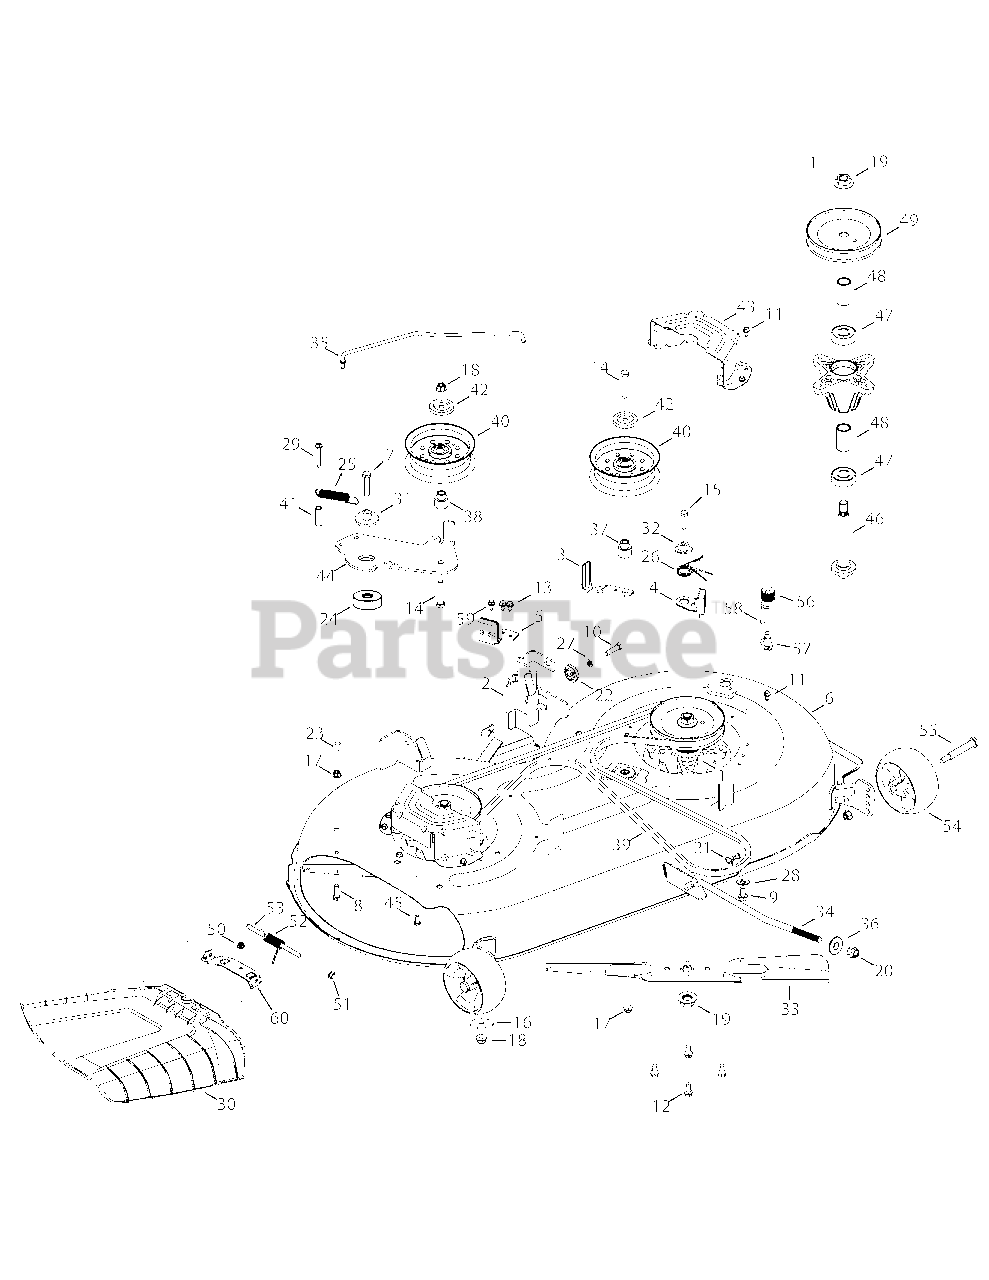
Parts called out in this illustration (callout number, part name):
1	Spindle Ass’y, Pulley, 6.2 Dia
2	Bracket Ass’y, Deck, Hanger LH
3	Belt Keeper
4	Brake Assembly, Deck, LH
5	Brake Assembly, Deck, RH
6	Deck, 42"
7	Hex Screw, 3/8-16 x 1.75
8	Hex Cap Screw, 5/16-18 x 1.00
9	Screw, Self-tapping, 5/16-18, .750
10	Hex Screw, 5/16-18, 1.25, Gr5, Std
11	Screw, Self-tapping, 1/4-20, 0.500
12	Screw, 5/16-18 x 0.750
13	Screw, M6-1 x .625
14	Hex Screw, 3/8-16, 2.00, Gr8, Std
15	Hex cap Screw, 5/16-18 x 1.25
16	Flat Washer, .406 x 1.50 x .105
17	Nut, Flange Lock, 5/16-18, Grf
18	Nut, Flange Lock, 3/8-16, Grf
19	Nut, Flange, 5/8-18
20	Flange Lock Nut, 1/2-13
21	Bow-Tie Cotter Pin
22	Gear, Deck, Adjustment
23	Cap, .290 x .500
24	Spacer, .385 x 1.75 x .585
25	Extension Spring, .750 X 4.77
26	Torsion Spring, LH
27	Washer, Lock, 5/16, Regular Duty
28	Flat Washer, .406 x .875 x .059
29	Screw, Self Tapping, 1/4-20, 1.50
30	Chute Deflector Assembly
31	Shoulder Spacer, .970 x .190
32	Shoulder Spacer, .75 x .145
33	Blade, Cut, 21.23" 2-In-1
34	Rod, Lift, Deck, Frt, 12.7
36	Deck Lift Pivot Cup
37	Shoulder Spacer, Idler
38	Shoulder Spacer, Pivot Idler
39	Belt, V Type, A Sec X 96.5
40	Pulley, Idler, 4.50"Dia
41	Spacer, .260 x .375 x 1.030
42	Pulley Cap
43	Deck Belt Cover, 42
44	Deck Idler Bracket
45	Hex Cap Screw, 1/4-20 x .62
46	Shift, Spindle, 6.11.
47	Bearing, Ball, .787id x 1.85 Odx.551
48	Spacer, .792 x 1.060 x 1.860
49	Pulley, Deck, 5.4 Dia
50	Nut, Flange Lock, 1/4-20, Nylon
51	Push Cap
52	Spring, Torsion, .440 ID x 1.75
54	Wheel, Deck, 5.0 Dia Ball
55	Bolt, Shoulder, .496 x 2.50, 3/8-16
56	Water Nozzle Adapter
57	Deck Wash Nozzle
58	Shoulder Screw, 1/4-20 x 0.50
59	Shoulder Screw, 1/4-20
